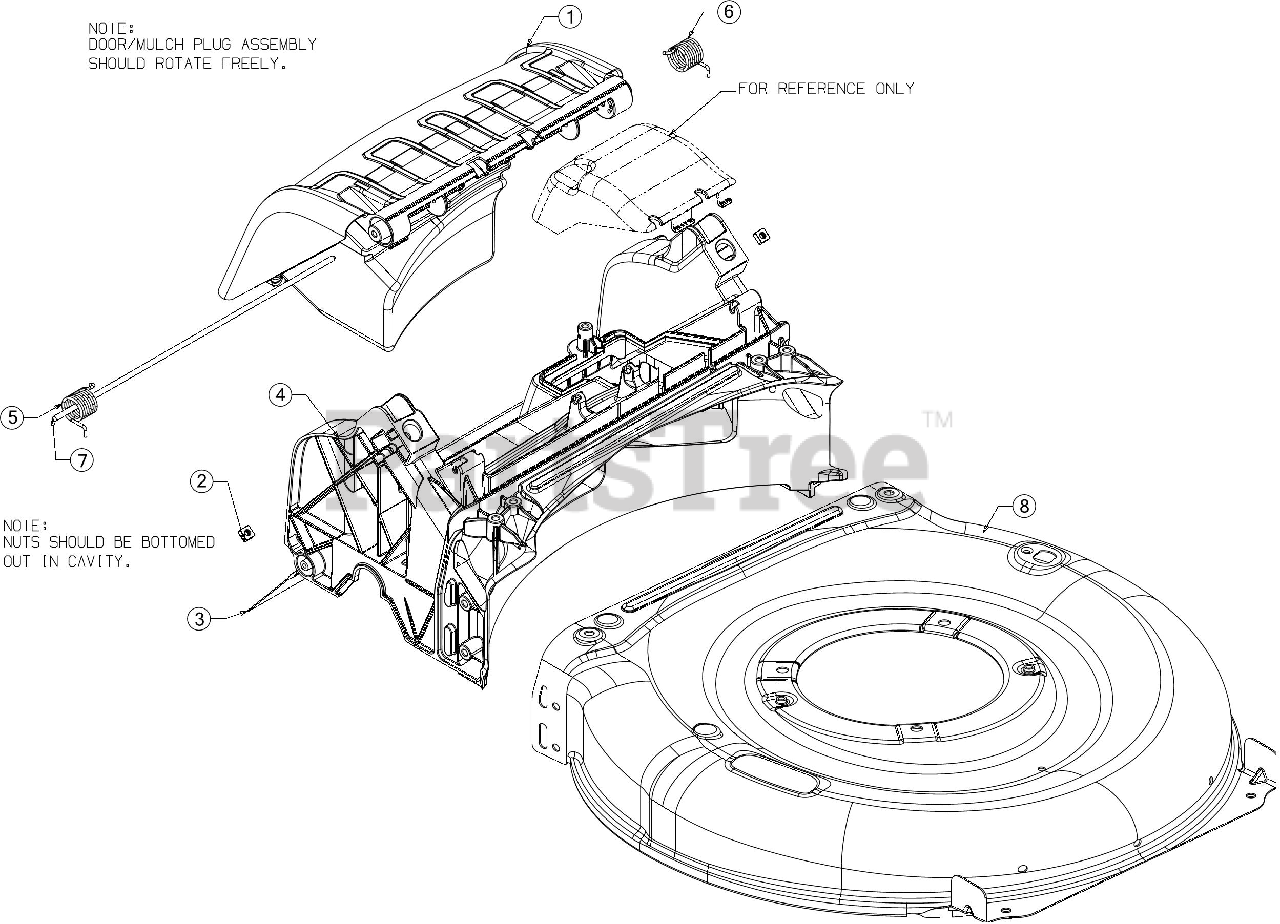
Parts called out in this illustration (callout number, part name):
1	DOOR ASSEMBLY
2	SQUARE NUT 1/4-20
3	TRAILSHIELD
4	REAR BAFFLE
5	TORSION SPRING (RH)
6	TORSION SPRING (LH)
7	REAR DOOR PIVOT ROD
